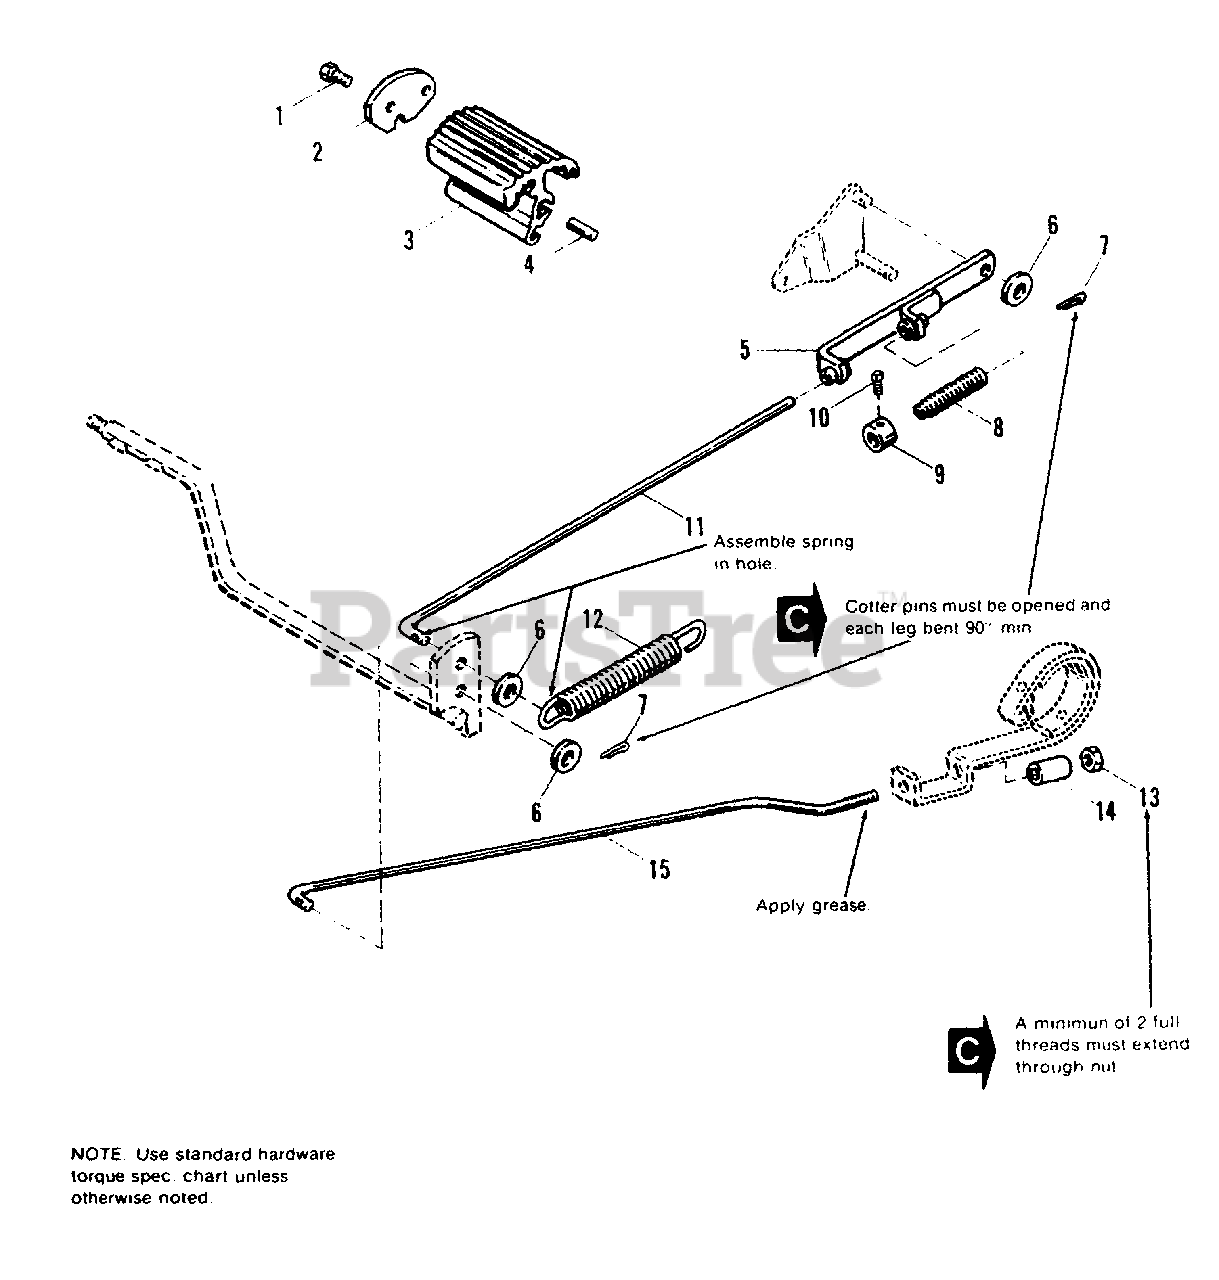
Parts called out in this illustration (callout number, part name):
1	SCREW, Hex, Taptite, 1/4-20 x 5/8
2	PLATE, End
3	PEDAL, Foot
4	DAMPER, Rubber
5	GUIDE ASSY., Rod
6	WASHER, Plain, 5/16
7	PIN, Cotter, 3/32 x 3/4
9	COLLAR, Set
10	SETSCREW, 1/4-20 x 3/8
11	ROD, Clutch
12	SPRING, Return
13	LOCKNUT, Esna, Hex, 3/8-16
15	ROD, Brake
